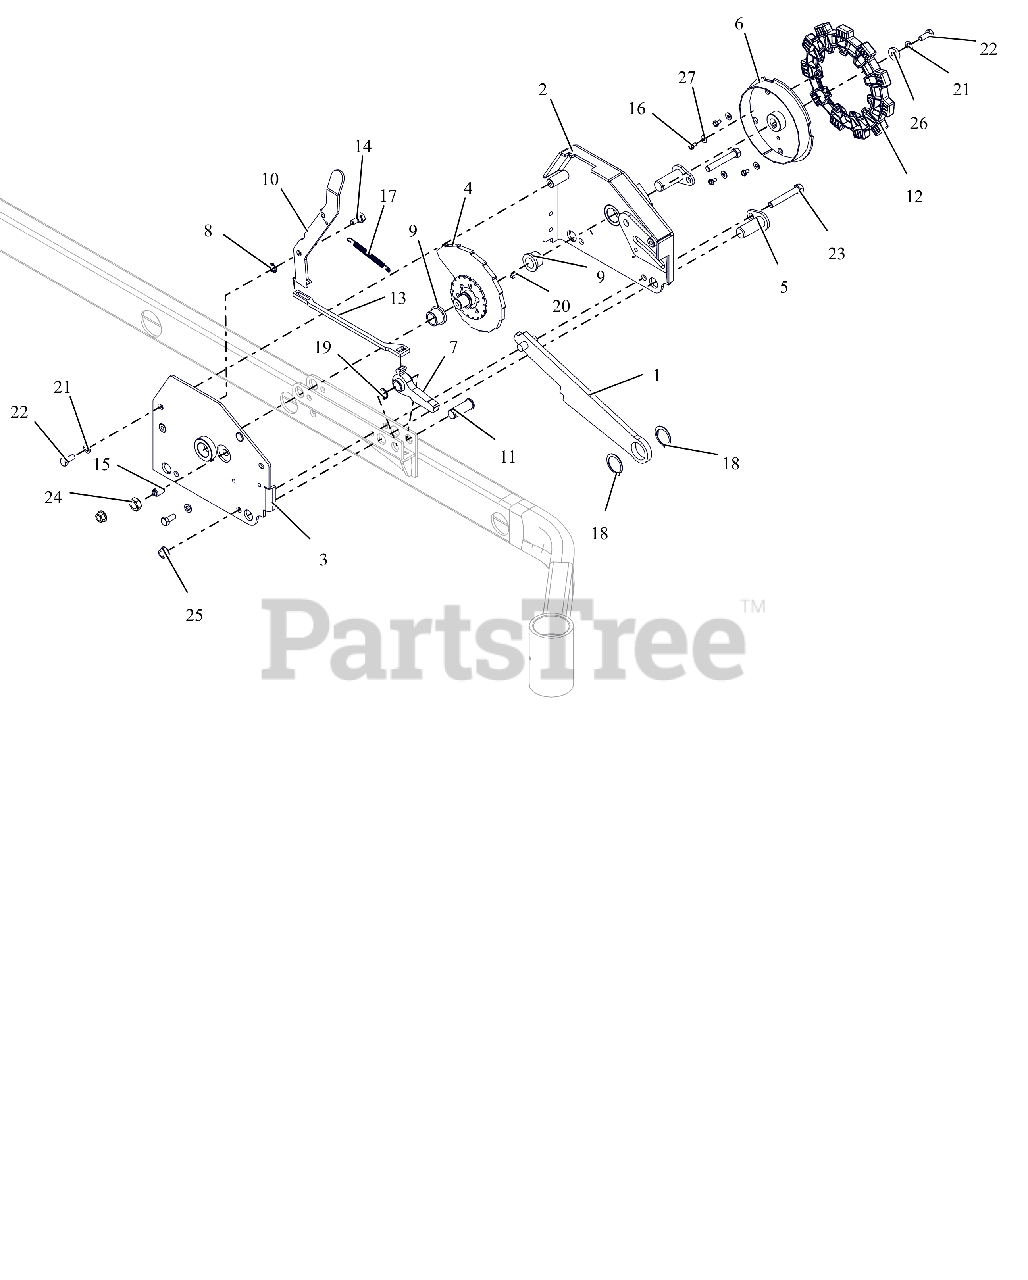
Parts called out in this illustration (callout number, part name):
1	HOC LINK WLDMT - BLK
2	HOC INNER WLDMT - RED
3	WLDMT, HOC OUTER
4	WLDMT, CAM, HOC
5	WLDMT, PIN HOC MOUNTING
6	WLDMT, PT400 HOC WHEEL
7	WMT, LOCK PAWL
8	WAVE WASHER .390X.655X.110
9	BUSHING, FLANGE .75X.75X1.0
10	LEVER, TRANSPORT LOCK
11	PIN, CLEVIS .625 SNAP RING
12	WHEEL, HOC
13	LINK, TRANSPORT LOCK
14	BOLT, SHLDR .31-18 X .25
15	BALL SPRING PLUNGER, .500-13
16	SCR-TAP 10-24X.375 PRE-COAT 80
17	SPRING, EXT
18	RG-RET-EXT 1.25 X .050
19	RG-RTNG-EXT .625X.050
20	KEY-SQ .188X.188X.375
21	WSHR,LK-REG .312X.078 ZCC
22	BLT,HEX .31-18X.75 G5 ZCC
23	BLT, HEX .38-16X2.50 G5 ZCC
24	NUT-JAM .500-13 G2 ZCC
25	NUT-LK-CTR-FLG .375-16 GF ZCC
26	WSHR, FLT .328X.870X.179 ZCC
27	WSHR, FLT .219X.500X.049 ZCC
